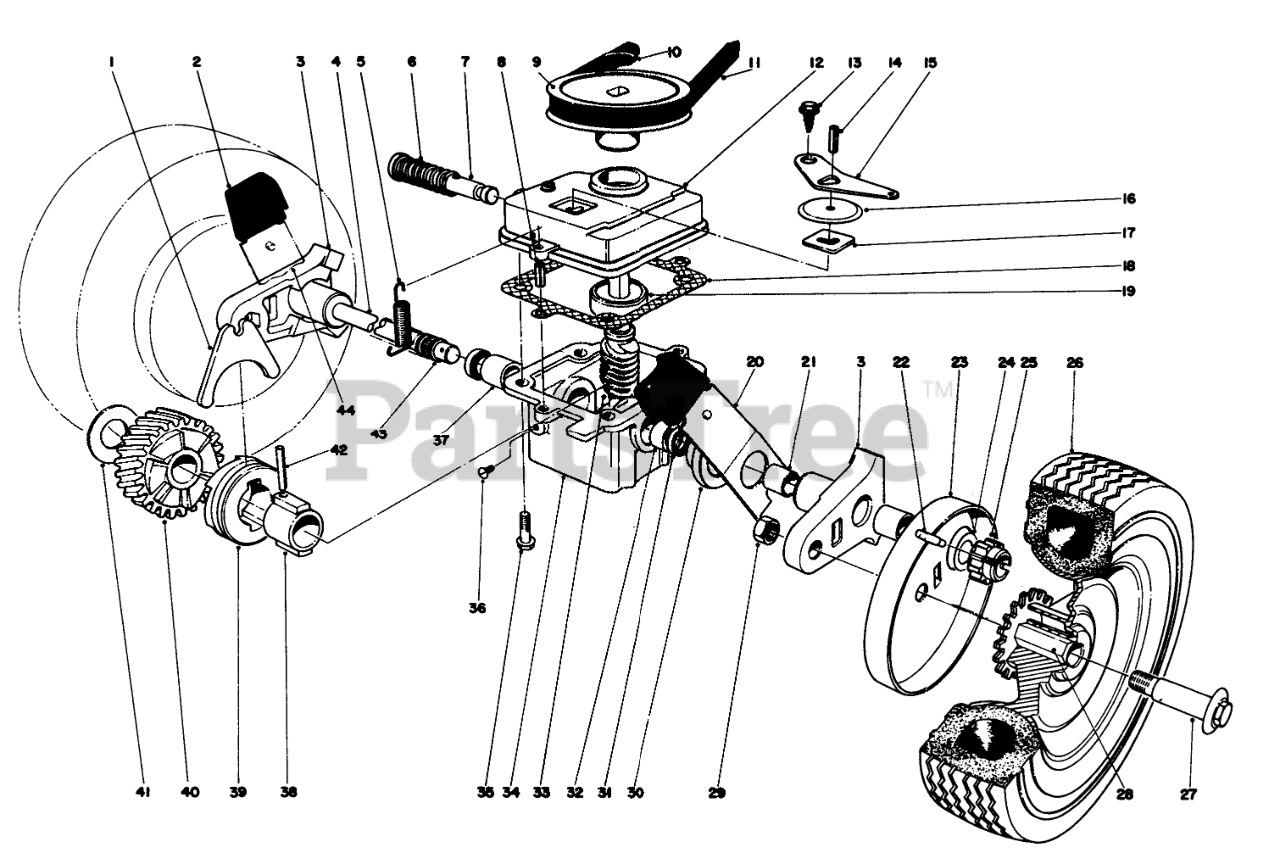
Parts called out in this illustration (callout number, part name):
1	SHIFTER FORK
2	KNOB-ARM
3	Pivot Arm (Incl. Ref. 21)
4	Drive Shaft
5	TENSION SPRING
6	SPRING
7	Shift Rod
8	3/16 X 1/2 ROLL PIN
9	PULLEY
10	PUSH-ON 93-3236
11	V BELT
12	GEAR CASE COVER
13	Screw
14	PIN-ROLL
15	SHIFTER ARM
16	TRANS DUST COVER
17	LATCH PLATE
18	GASKET
19	Bearing
20	SPRING ARM ASM SP LH
21	BUSHING
22	PIN-GROOVED
23	WHEEL COVER
24	WASHER-THRUST
25	Pinion
26	Bushing
28	WHEEL BUSHING
29	Nut
30	End Cap
31	Seal
32	Bushing
33	WORM SHAFT
34	Gear Case (Incl. Ref. #31-32 & 37)
35	Screw
36	NYLON SCREW
37	Bushing
38	SLEEVE
39	CLUTCH JAW
41	THRUST WASHER
42	COIL PIN
43	COVER-SHAFT, DRIVE
44	SPRING ARM ASM SP RH
